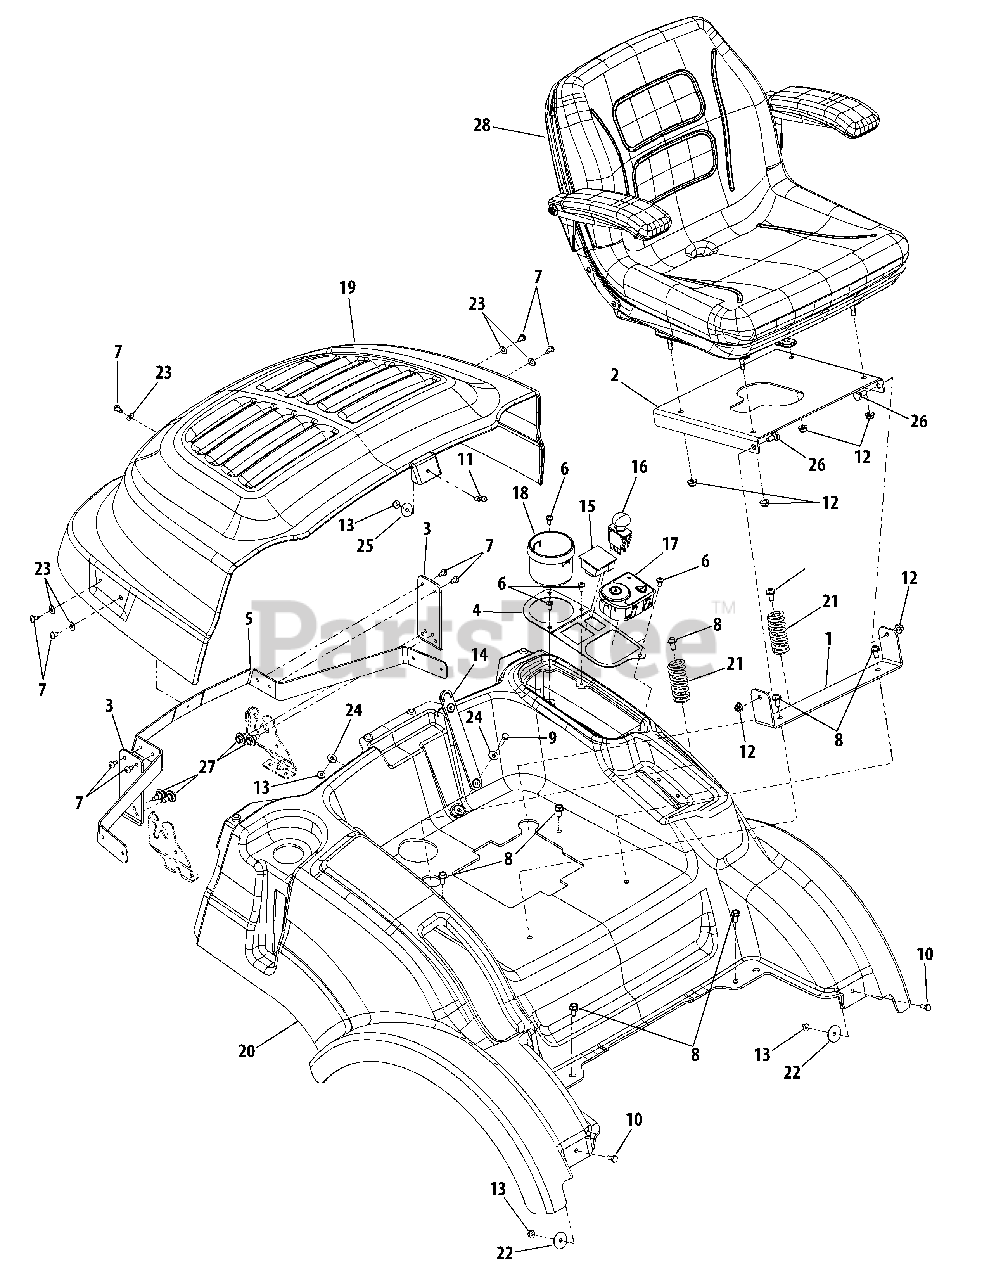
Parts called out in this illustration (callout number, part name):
7	Screw, Pan Hd. Torx, 1/4-20 x .5
8	Screw, Hex Wash Hd. Tapp, 5/16-18 x .75
9	Screw, Hex Cap, 1/4-20 x 1.0 Gr5
10	Screw, Hex Cap, 1/4-20 x .75 Gr5
11	Pin, Grasscatcher 1/4-20
12	Nut, Hex Insert Flange Lock, 5/16-18 GrF
13	Nut, Hex Insert Flange Lock, 1/4-20 GrF
14	Strap, Hood
15	Meter, Indicator/Hour
16	Switch, Electric PTO
17	Module, Key Switch
18	Holder, Cup
21	Spring, Compression, 1.28 x 3.125
22	Washer, Flat, .285 x 1.25 x .06
23	Washer, Flat, .25 x .63 x .0515
24	Washer, Flat, .26 x .72 x .60
25	Washer, Flat, .265 x 1.0 x .030 HT
26	Screw, Shoulder, .435 x .178:5/16-18
27	Screw, Shoulder, .43 x .29:TT:5/16-18
28	Seat, w/Arm Rests
